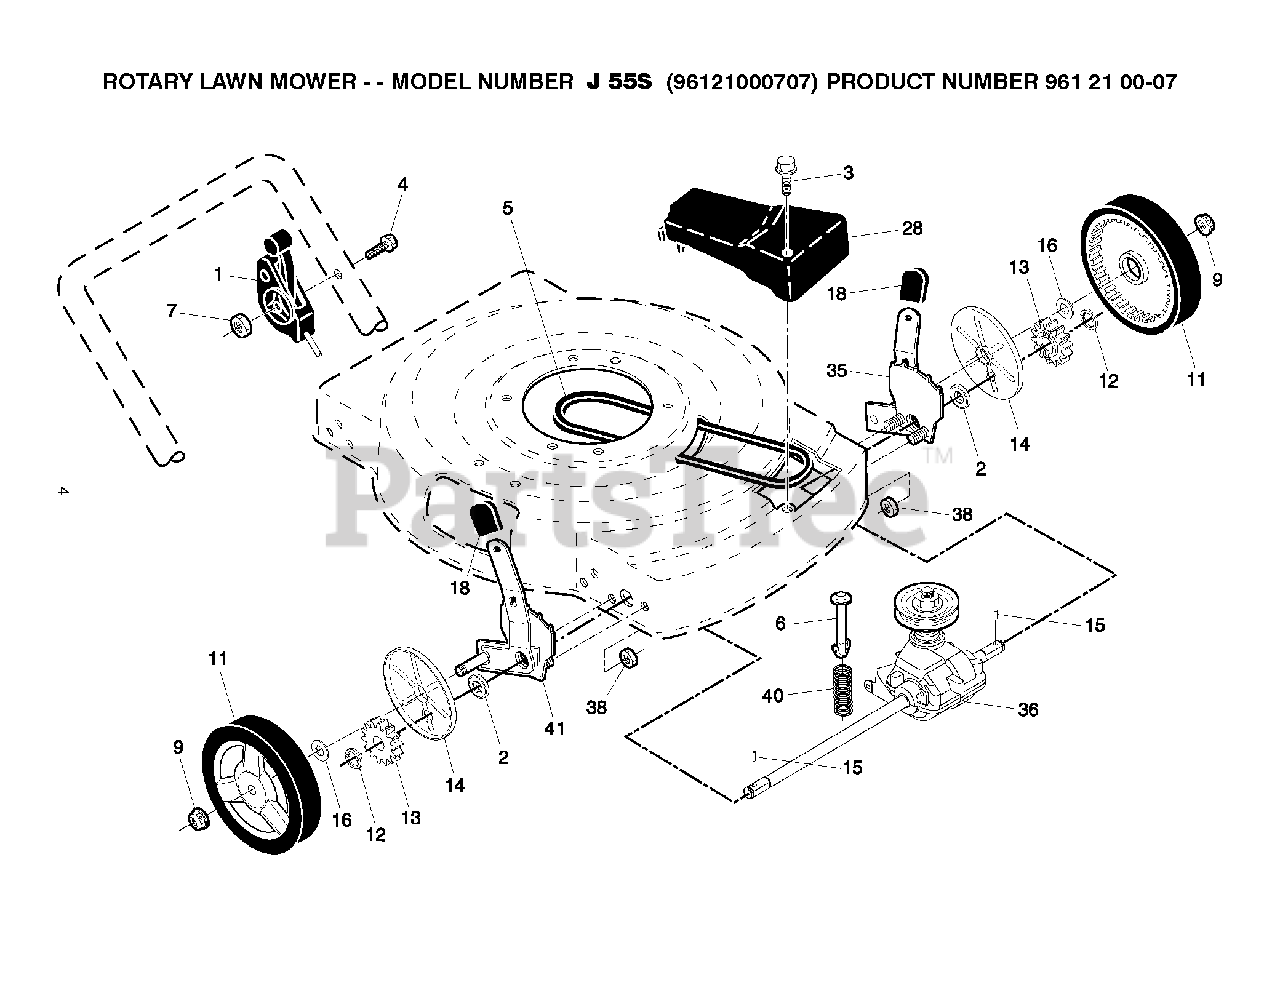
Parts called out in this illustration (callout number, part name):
1	DRIVE CONTROL 59.8 FWGD
2	BEARING.ASM.
5	BELT THERM .32
6	SPRING RETAINER
7	NUT.HEX.FLANGE.1/4
9	NUT.HEX.FLANGE.3/8-16.LOCKNUT
12	E-RING 7/16 RE
13	PINION.14.TEETH.FGD
14	COVER.DUST.WHEEL
15	PAWL, DRIVE
16	WASHER FLUT
18	SELECTOR KNOB
35	KIT ADJUSTER ASM.438151.LT
36	TRANSMISSION.22.FGD/W/PULLEY
38	LOCKNUT
40	SPRING.EXTENSION
41	KIT ADJUSTER ASM.438148 .RT
